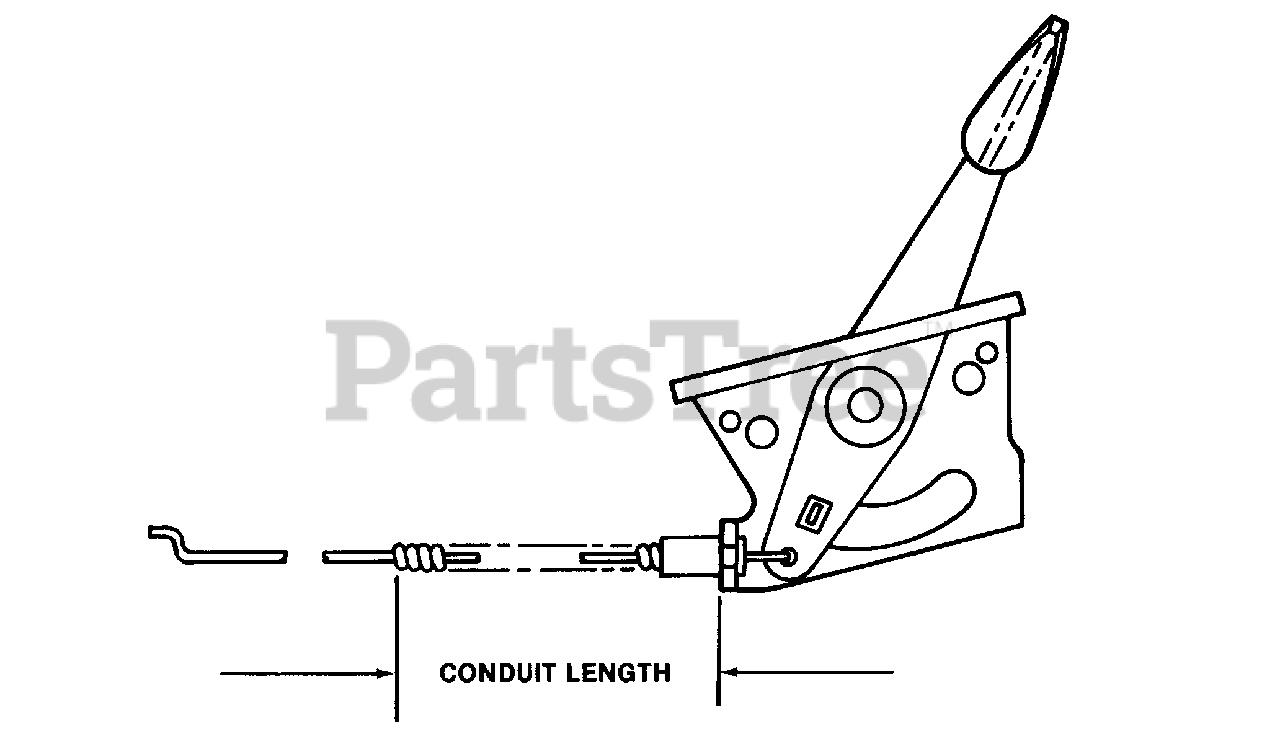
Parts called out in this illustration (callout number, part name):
1	CONTROL, Throttle (Briggs 4 cycle, 45.25")
1	CONTROL, Throttle (Briggs 4 cycle, 46.5")
1	CONTROL, Throttle (Tecumseh 2 cycle, 62.0")
1	CONTROL, Throttle (Tecumseh 4 cycle, 42.5")
1	CONTROL, Throttle (Tecumseh 4 cycle, 44.5")
1	CONTROL, Throttle (Robin 4 cycle, 40.75")
1	CONTROL, Throttle (Robin 2 cycle, 42.75")
2	ENGINE, Briggs (Model 90702-3080-01) 3.5 HP
2	ENGINE, Briggs (Model 90702-3105-01) 3.5 HP
2	ENGINE, Briggs (Model 92902-3176-01) 3.5 HP
2	ENGINE, Briggs (Model 92902-3271-01) 3.5 HP
2	ENGINE, Briggs (Model 92902-3912-01) 3.5 HP
2	ENGINE, Briggs (Model 92902-3914-01) 3.5 HP
2	ENGINE, Briggs (Model 110902-3189-01) 4 HP
2	ENGINE, Briggs (Model 110902-3911-01) 4 HP
2	ENGINE, Briggs (Model 110902-3914-01) 4 HP
2	ENGINE, Briggs (Model 110907-3913-01) 4 HP Electric Start
2	ENGINE, Briggs (Model 111702-3047-01) 4 HP
2	ENGINE, Briggs (Model 111702-3057-01) 4 HP
2	ENGINE, Briggs (Model 111707-3048-01) 4 HP Electric Start
2	ENGINE, Briggs (Model 111707-3058-01) 4 HP Electric Start
2	ENGINE, Briggs (Model 114702-3030-01) 4 HP IC
2	ENGINE, Briggs (Model 114702-3031-01) 4 HP IC Electric Start
2	ENGINE, Briggs (Model 114707-3031-01) 4 HP XL
2	ENGINE, Briggs (Model 114902-3137-01) 4 HP
2	ENGINE, Briggs (Model 114902-3150-01) 4 HP IC
2	ENGINE, Briggs (Model 114902-3156-01) 4 HP
2	ENGINE, Briggs (Model 131922-0169-01) 4 HP IC
2	ENGINE, Briggs (Model 96722-3206-01) 4 HP 2 Cycle
2	ENGINE, Tecumseh (Model TVS90-43179D) 3.5 HP
2	ENGINE, Tecumseh (Model TVS90-43180D) 3.5 HP Electric Start
2	ENGINE, Tecumseh (Model TVS90-43248D) 3.5 HP
2	ENGINE, Tecumseh (Model TVS90-43249D) 3.5 HP Electric Start
2	ENGINE, Tecumseh (Model TVS105-53069D) 4 HP
2	ENGINE, Tecumseh (Model TVS105-53072D) 4 HP
2	ENGINE, Tecumseh (Model TVS105-53072E) 4 HP
2	ENGINE, Tecumseh (Model TVS105-53073D) 4 HP Electric Start
2	ENGINE, Tecumseh (Model TVS105-53105F) 4 HP Electric Start
2	ENGINE, Tecumseh (Model TVS105XL-54018B) 4 HP Electric Start
2	ENGINE, Tecumseh (Model TVS105XL-54018C) 4 HP Electric Start
2	ENGINE, Tecumseh (Model TVXL105-54022B) 4 HP
2	ENGINE, Tecumseh (Model TVS840-8011A) 4 HP 2 Cycle
2	ENGINE, Tecumseh (Model TVS840-8011B) 4 HP 2 Cycle
2	ENGINE, Robin (Model W1-145V) 4 HP
2	ENGINE, Robin (Model W1-185V) 4 HP
2	ENGINE, Robin (Model WT1-125V) 4 HP 2 Cycle
